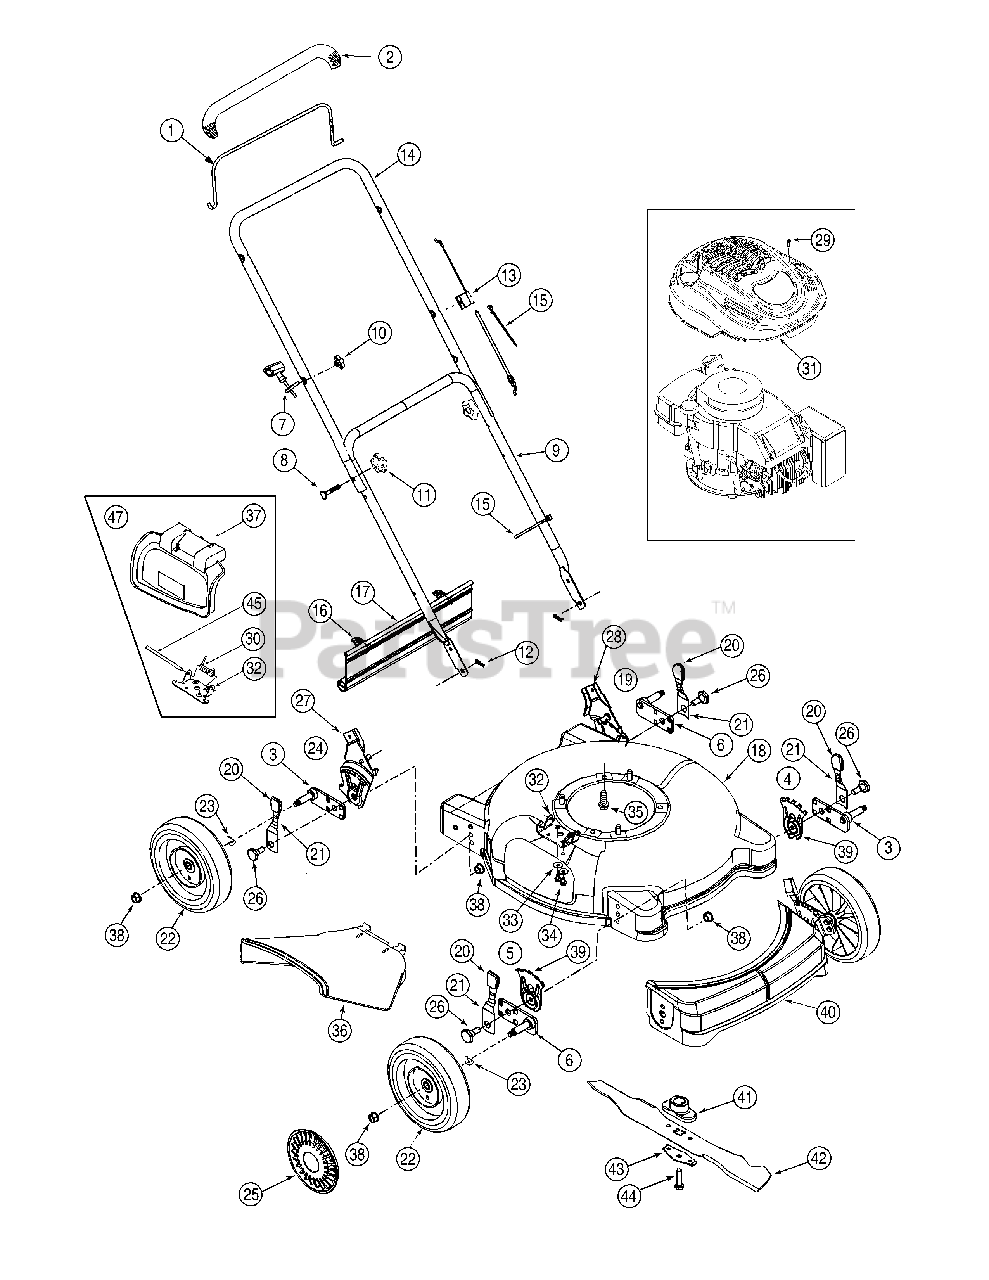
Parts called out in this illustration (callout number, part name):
1	Blade Control Handle
2	Deluxe Cover - Black
2	Deluxe Cover - Red
2	Deluxe Cover - Grey
4	Hgt. Adjust Ass’y LH
5	Hgt. Adjust Ass’y RH
7	Rope Guide Bolt
8	Carriage Bolt 5/16-18 x 2.0
10	Knob - ERS Guide 1/4-20
11	Knob - Star 5/16-18
12	Int. Cotter Pin .072 x 1.13" Lg.
13	Control Cable 53.0" Lg. (Tec)
13	Control Cable 40.0" Lg. (Kawasaki)
13	Control Cable 37.25 " Lg. (Honda)
15	Cable Tie
19	Rear Hgt. Adjust Ass’y LH
20	Knob
21	Spring Lever
22	Wheel Ass'y 8" x 2.125" Idle BB
22	Wheel Ass'y 8" x 2.0" S-Wave BB
23	Wave Washer .51" ID (w/bb wheels)
24	Rear Hgt. Adjust Ass’y RH
25	Hub Cap - Yellow Radial (optional)
25	Hub Cap - Grey Radial (optional)
25	Hub Cap - Beige Radial (optional)
26	Shoul der Screw .50 Dia. x .385
27	Adjust/Brkt. Ass’y RH
28	Adjust/Brkt. Ass’y LH
30	Torsion Spring
31	Shroud - Yellow
33	Cupped Washer .265 ID x .75 OD
34	Hex Wash S-Tapp Scr 1/4-20 x .50
35	Hex Wash HD Tap Scr 3/8-16 x .88
36	Chute Deflector
37	Mulching Plug
38	Flanged Lock Nut 3/8-16 Gr. F
39	Height Adjuster Plate
40	Front End Cover -Yellow (optional)
40	Front End Cover-Black (optional)
41	Blade Adapter
42	20" Mulching Blade
43	Blade Bell Support
44	Hex Bolt 3/8-24 x 1.5" Lg. (Grade 8)
45	Hinge Pin
47	Hinged Mulching Plug Ass'y
